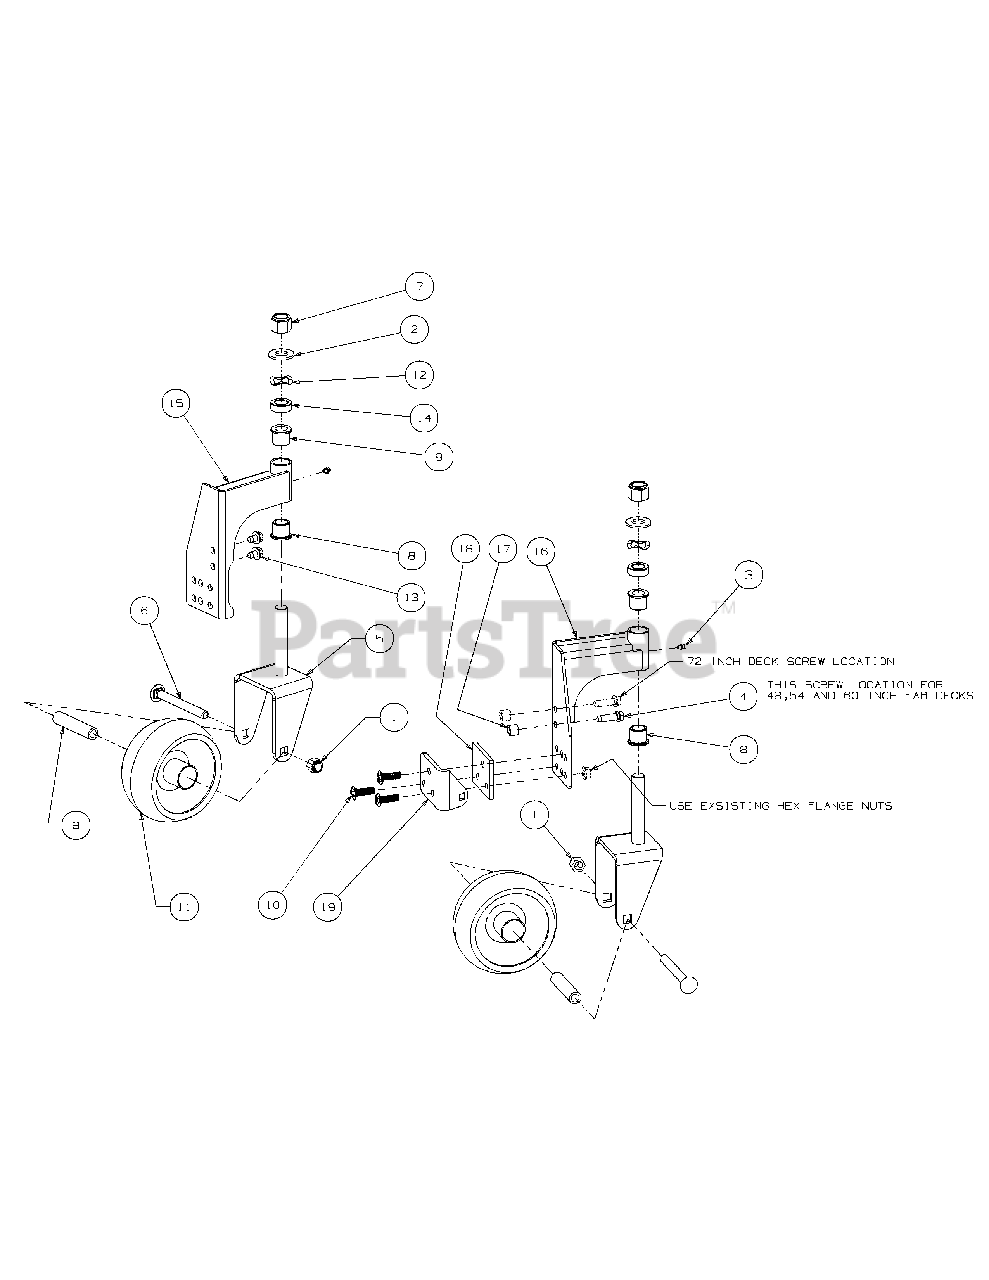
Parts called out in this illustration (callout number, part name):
1	Nylock Nut:1/2-13
2	Flat Washer, .750 x 1.50 x .120
3	Grease Fitting, 1/4-28 x 3/16
4	Self Tapping Screw, 3/8-16 x 1.250
6	Carriage Screw, 1/2-13 x 4.50
7	Nut, 3/4-10, Hex Lock
8	Flange Bearing, .754 ID x 1.00 OD x .925
9	Axle, Caster Wheel
10	Carriage Screw, 3/8-16 x 1.25
11	Wheel Assembly, 6.25 x 3.00-4
12	Wave Washer, 1.38 OD x .88 ID x .02
13	Self Tapping Screw, 3/8-16 x .500
14	Spacer, .76 ID x 1.25 OD x .44
